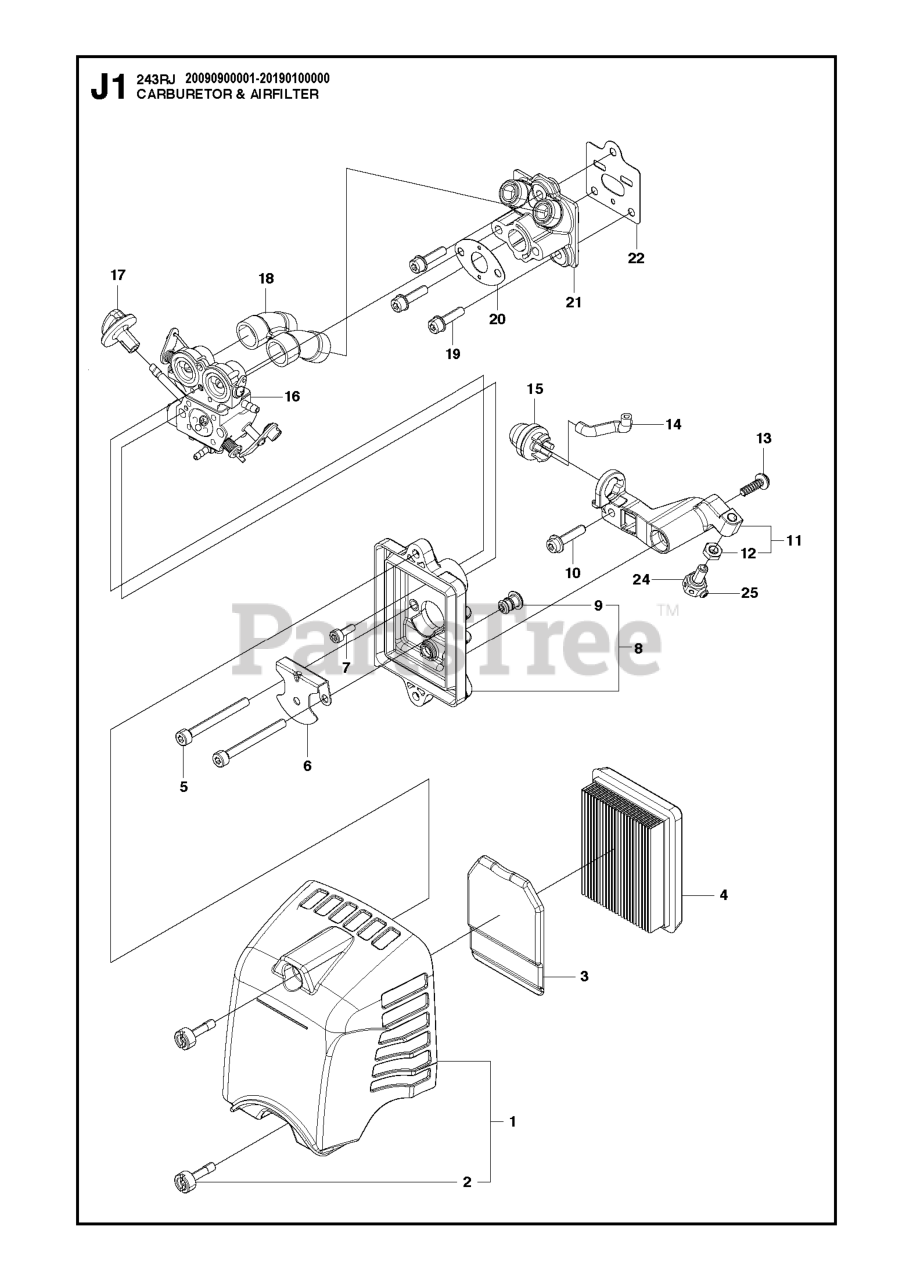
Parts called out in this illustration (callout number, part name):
7	BOLT M4 X 12 T27
11	BRACKET ASSY
15	AIR PURGE BUBBLE
19	BOLT, TORX
24	SCREW CABLE ADJUST
